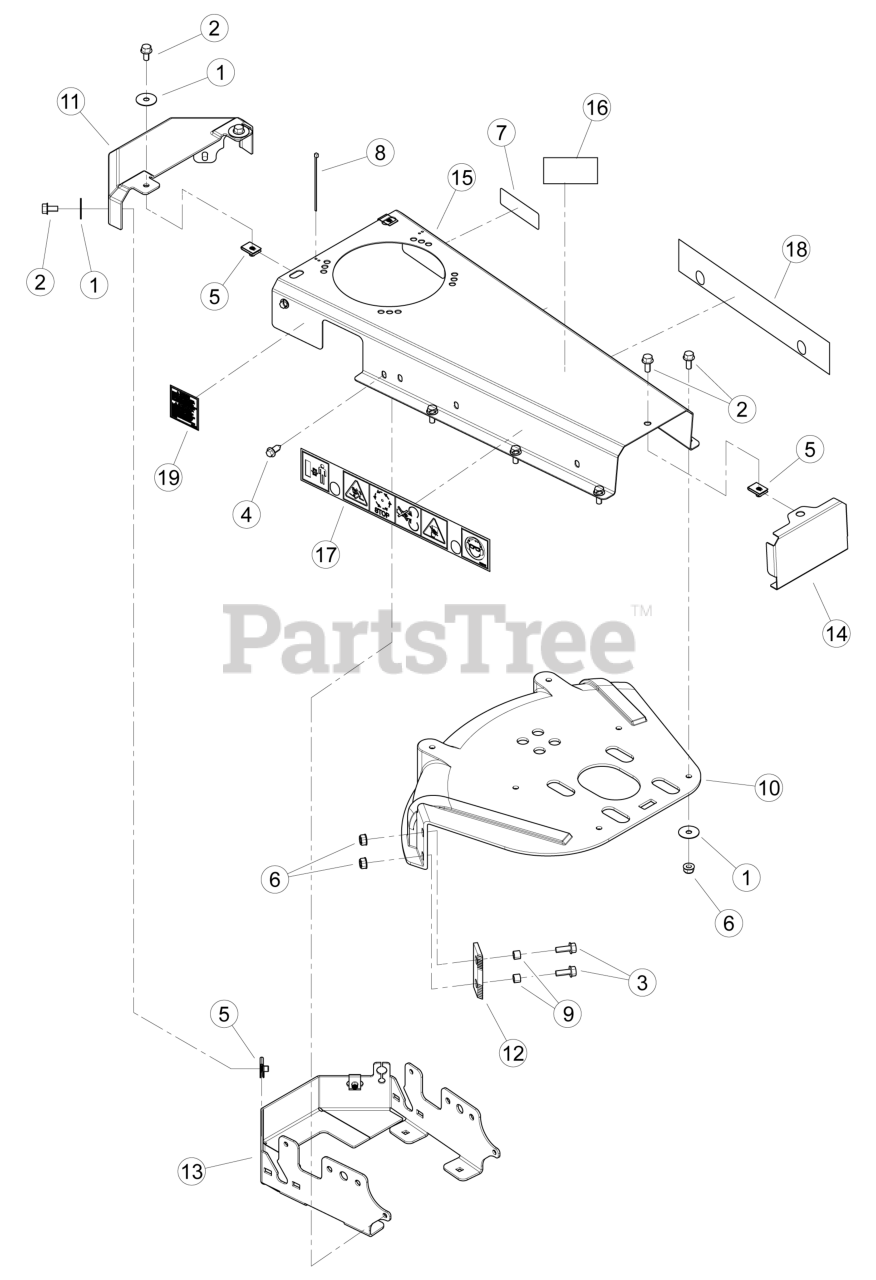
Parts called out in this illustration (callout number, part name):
1	WASHER, 5/16" FENDER ZP
2	BOLT, 5/16 × 3/4 FLANGE NC
3	BOLT, 5/16 × 7/8 FLANGE NC
4	SCREW, 11/32-12 × 7/8 FLANGE T-AB
5	NUT 5/16"-18 TINNERMAN U-TYPE
6	NUT, 5/16-18 NYLOCK FLANGE
7	DECAL, SERIAL NUMBER
8	STRAP,4 IN BLACK
9	SPACER, PLASTIC TRIMMER SHIELD
10	SHIELD, TRIMMER
11	COVER, WT TRANSMISSION
12	KNIFE, RECTANGULAR SHREDDING
13	BRACKET, WT TRANS MOUNT
14	COVER, METAL HW TRIMMERS
15	ASSEMBLY, WT BODY WITH DECALS
16	DECAL, MODEL ECHO WT-1610SP
17	DECAL, HW SAFETY INFORMATION
18	DECAL, HW MAINTENANCE INFORMATION
19	DECAL, SPARK ARRESTOR
